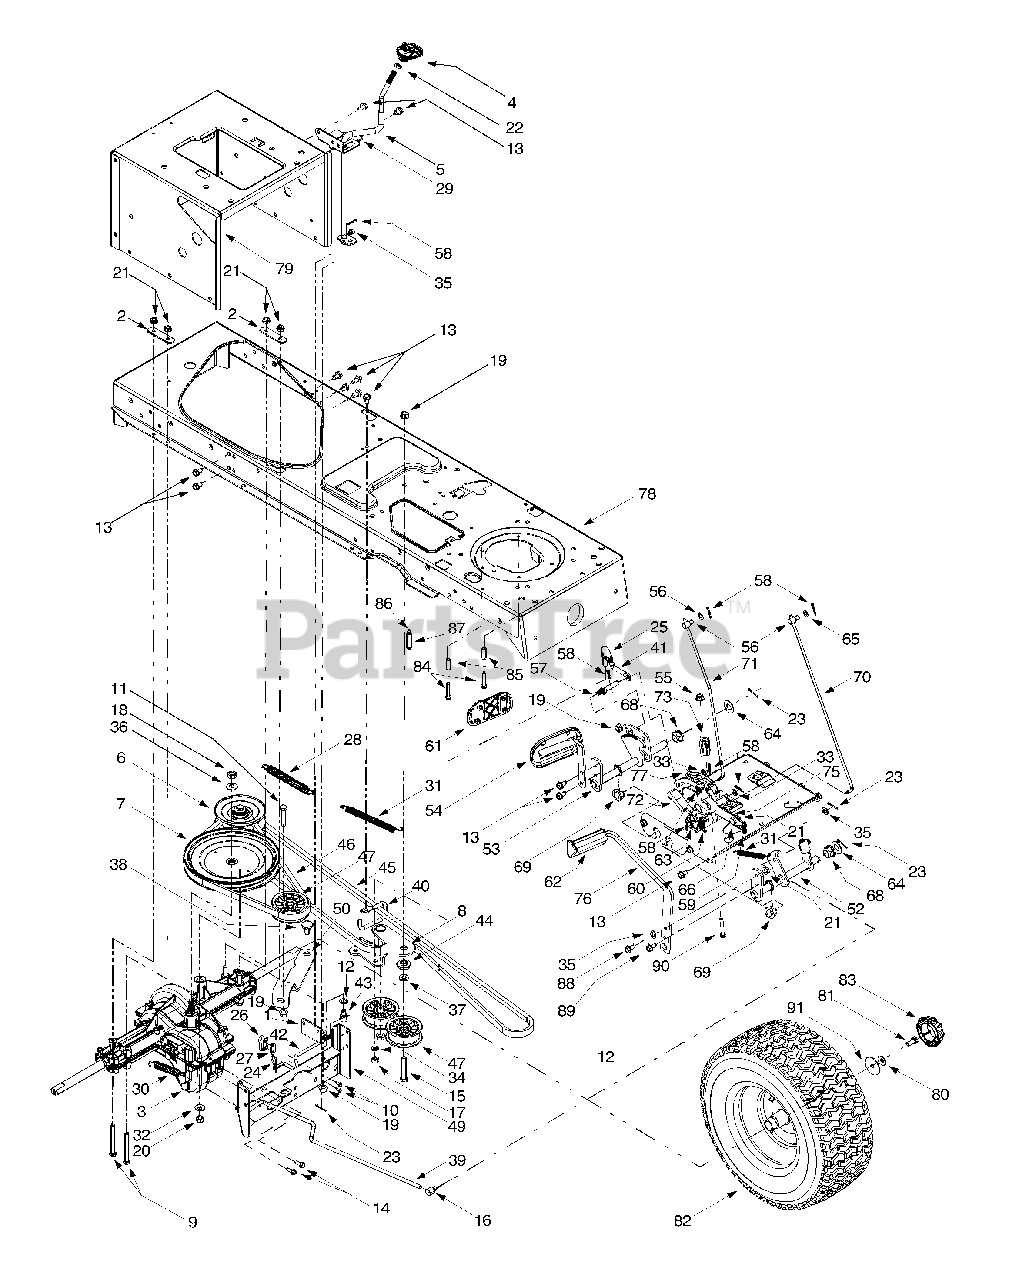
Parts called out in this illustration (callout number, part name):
3	Single-speed Transmission Assembly
4	Shifter Knob
5	Shift Lever
6	Variable-speed Pulley Assembly
7	Transmission Pulley, 8.5 x .5-36
8	Double-idler Bracket
9	Hex Cap Screw, 5/16-18 x 3
10	Self-tapping Screw, #8-18 x .5
11	Hex Cap Screw, 3/8-16 x 1.75
12	Flat Washer, .51 x 1.0 x .060
13	Self-tapping Screw, 5/16-18 x .625
14	Self-tapping Screw, 1/4-20 x .75
15	Hex Cap Screw, 3/8-16 x 2.25
16	Ferrule, 5/16-18
17	Hex Nut, 3/8-24
18	Hex Nut, 7/16-20
19	Flange Lock Nut, 3/8-16
20	Hex Nut, 3/8-16
21	Flange Lock Nut, 5/16-18
22	Jam Nut, 3/8-16
23	Cotter Pin
24	Internal Cotter Pin
25	Ball Joint
26	Short Spring Switch
27	Insulator Nut Plate
28	Extension Spring, .62 Dia. x 6.12
29	Compression Spring Clip
30	Extension Spring, .59 OD x 4
31	Extension Spring, .50 Dia. x 6.37
32	Bell Washer, .401 x .87 x .063
33	Flat Washer, .385 x .62 x .063
34	Lock Washer, 3/8
35	Flat Washer, 5/16
36	Bell Washer, .45 x 1.0 x .602
37	Flat Washer, .407 x .812 x .135
38	Shoulder Screw, .625 x .217
39	Brake Rod
40	Belt Guard
41	Idler Adjustment Rod, 3/8
42	Shift Rod
43	Adjustment Ferrule, 1/4-20 x 1.0
44	Shoulder Spacer, .38 ID
45	Variable-speed Belt
46	Drive Belt
47	Flat Idler, 2.75 OD
51	Adjustable Shift Bracket
52	Brake Control Assembly
53	Speed Control Assembly
54	Auto Drive - Pedal Assembly
55	Flange Lock Nut, 3/8-16
56	Ferrule, 1/4-20
57	Pin, 3/8-16 x 2.43
58	Cotter Pin
59	Compression Spring, .34 OD x 1.0
60	Extension Spring, .50 OD x 1.41
61	Auto Drive - Pedal Pad
62	Brake Pedal Pad
63	Flat Washer, .281 x .5 x .0625
64	Flat Washer, .64 x 1.24 x .06
65	Flat Washer, .344 x .062 x .03
66	Shoulder Screw, .437 x 1.62
67	Shoulder Screw, .5 x .434
68	Hex Flange Bearing
69	Split Hex Flange Bearing
70	Cruise Control Rod
71	Brake Lock Control Rod
72	Cruise Latch
73	Spacer, 5/16 x 1.54
74	Stearing Support Bracket
75	Auto Drive - Lockout Bracket
81	Hex Cap Screw, 5/16-24 x .75
83	Hub Cap
84	Self-tapping Screw, 1/4-20 x 1.5
85	Spacer
86	Self-tapping Screw, 1/4-20 x 1.75
87	Spacer
88	Self-tapping Screw, 5/16-18 x .75
89	Self-tapping Screw, 5/16-18 x .875
90	Hex Cap Screw, 3/8-16 x 2.5
91	Flat Washer, .350 x 1.59 x .062
